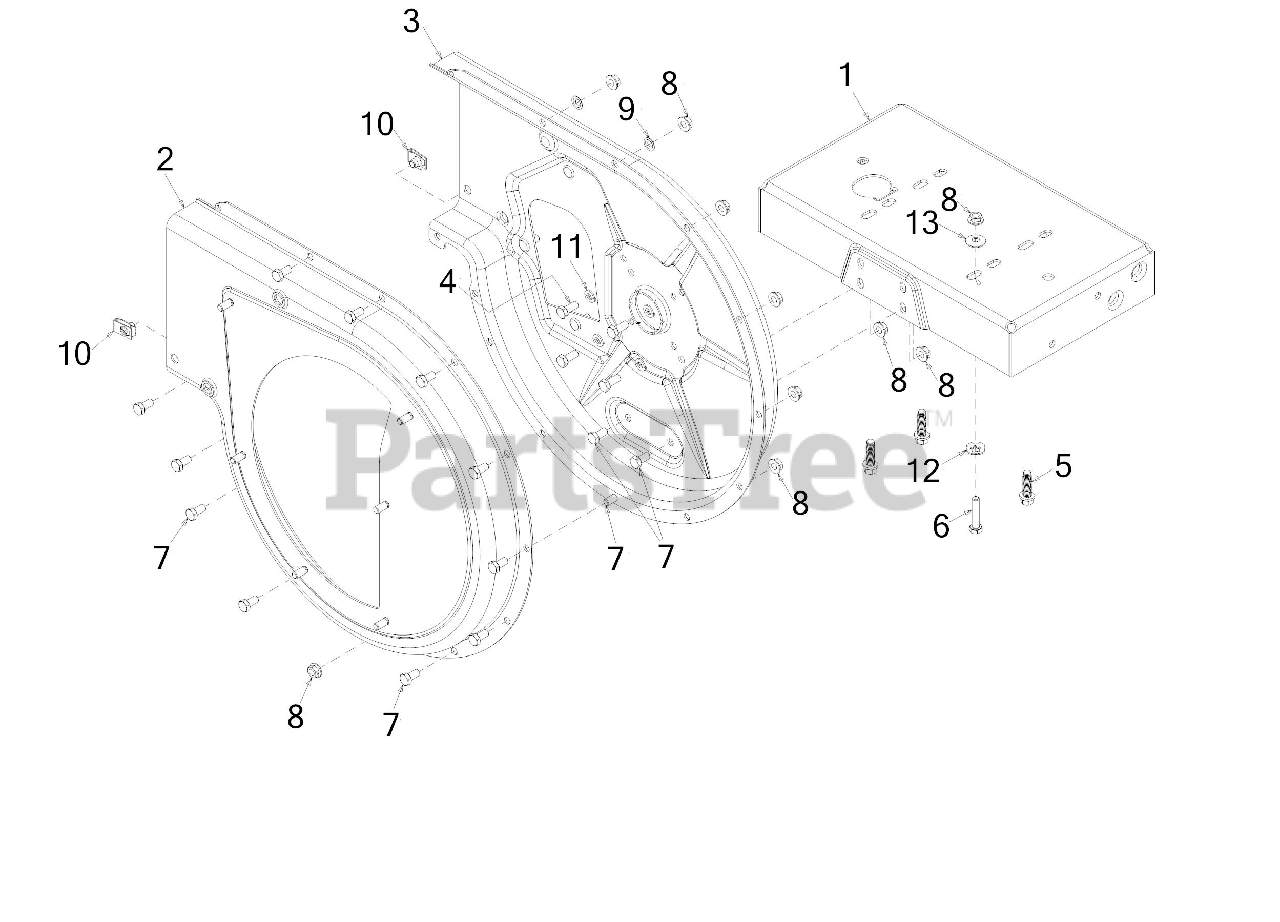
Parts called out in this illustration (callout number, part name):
1	FRAME ASSEMBLY
2	FLAIL HOUSING ASSEMBLY (OUTER)
4	HEX SCREW 5/16-24 x .75
5	SCREW 3/8-16 x 1.250
6	SCREW 5/16-18 x 1.5 LG
7	SCREW 5/16-18X .625 GR5
8	HEX FLANGE NUT
10	U-NUT
11	LOCK WASHER 5/16
12	SPECIAL WASHER
13	BELL WASHER .337 X.867 x .057
